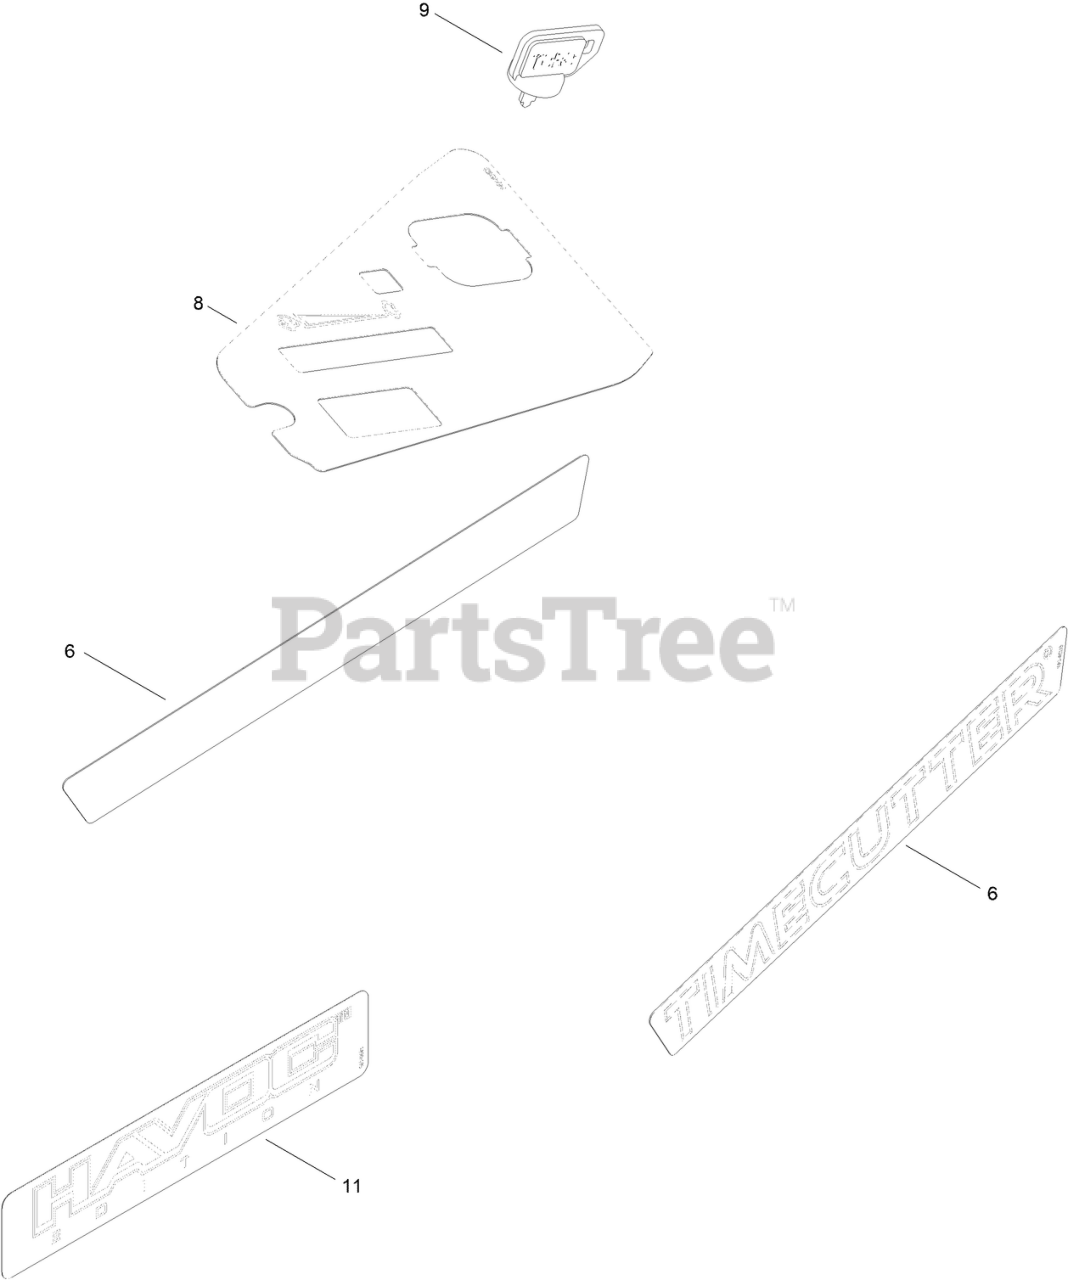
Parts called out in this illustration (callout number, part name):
6	DECAL - TIMECUTTER
8	DECAL - CONTROL PANEL W/OUT HOUR METER
9	KEY-IGNITION
11	DECAL-HAVOC
